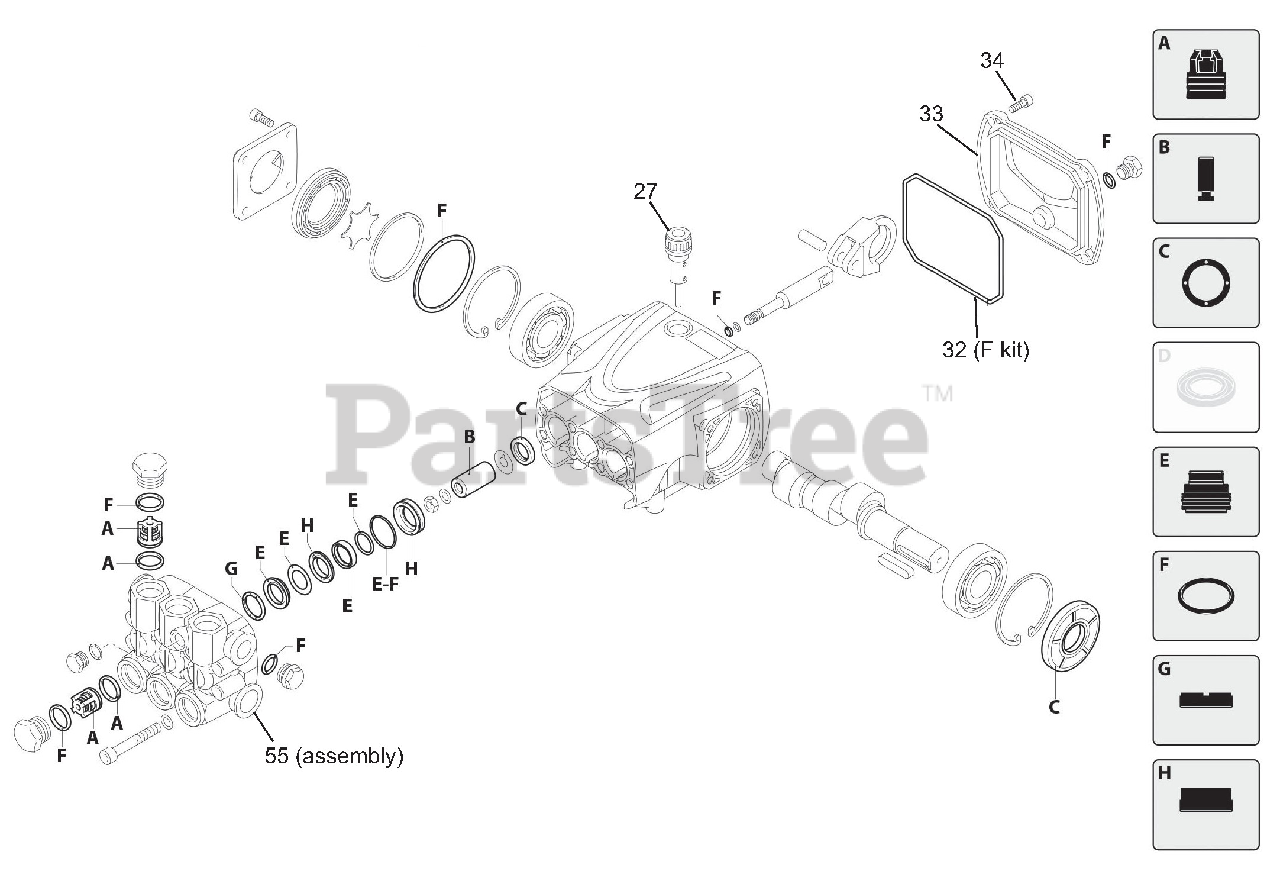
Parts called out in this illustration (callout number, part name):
34	COVER SCREW
55	HEAD ASSEMBLY
C	OIL SEALS
E	WATER SEALS
G	SUPPORT RINGS
H	PISTON GUIDES
